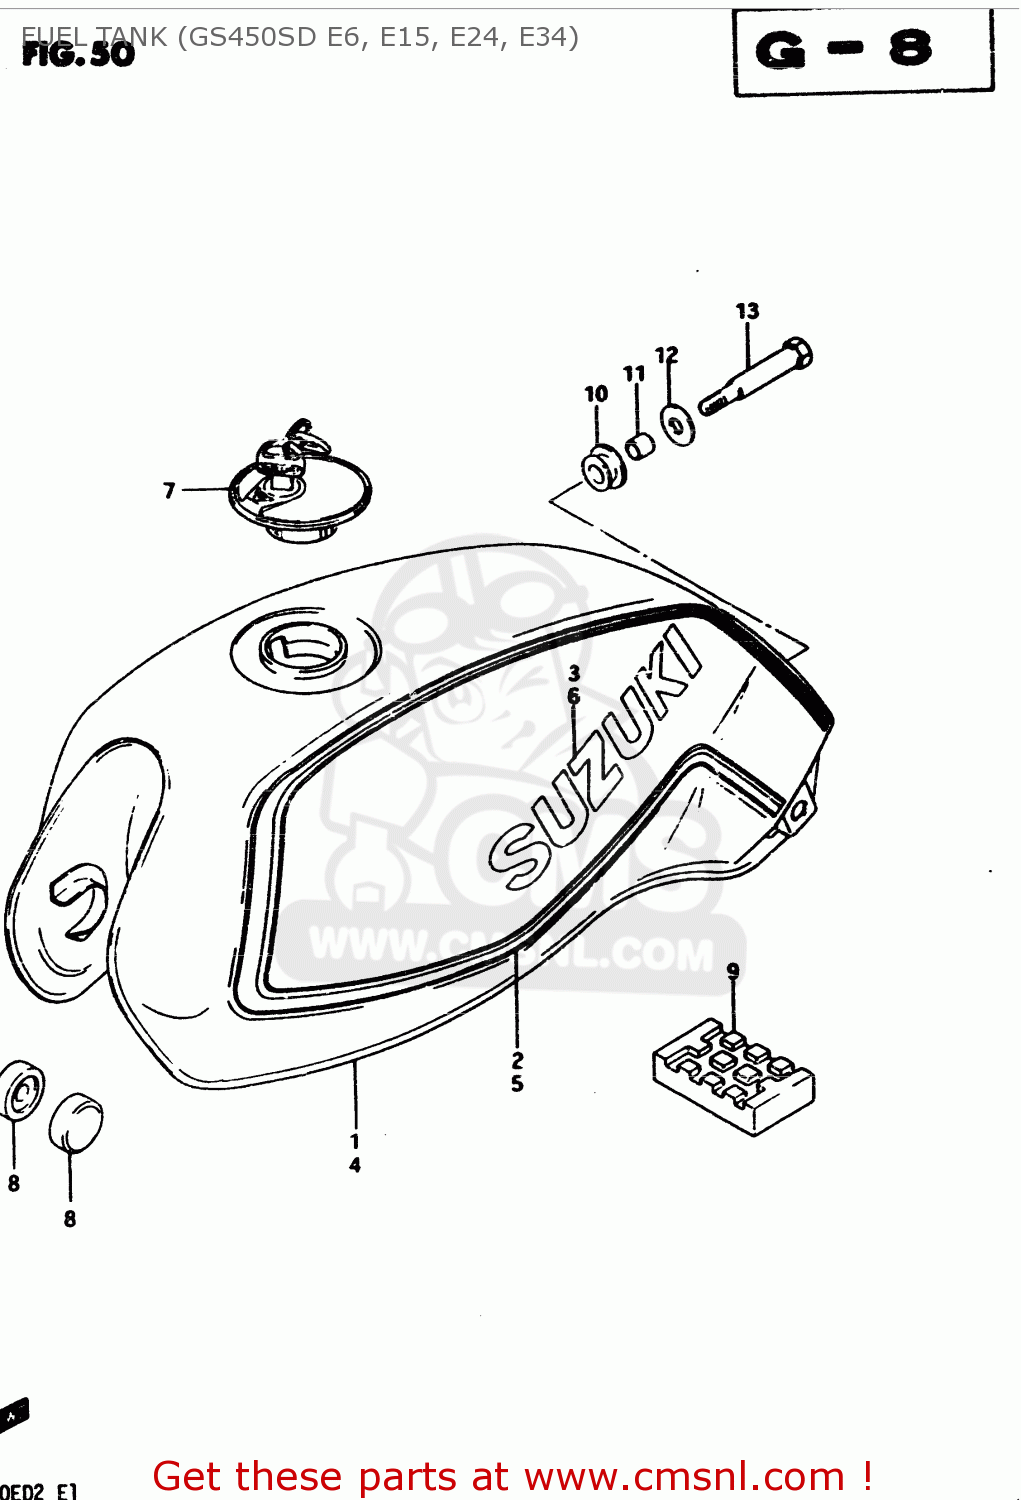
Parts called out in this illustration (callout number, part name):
1	TANK SET, FUEL
2	TAPE SET, FUEL TANK
3	EMBLEM(SILVER)
4	TANK SET, FUEL
5	TAPE SET, FUEL TANK
6	EMBLEM (WHITE)
7	CAP SET,FUEL TANK
8	CUSHION
9	CUSHION,FUEL TANK CTR
10	CUSHION
11	SPACER (6.8X10X10)
12	WASHER (6.5X29X1.6)
13	BOLT(6X60)
